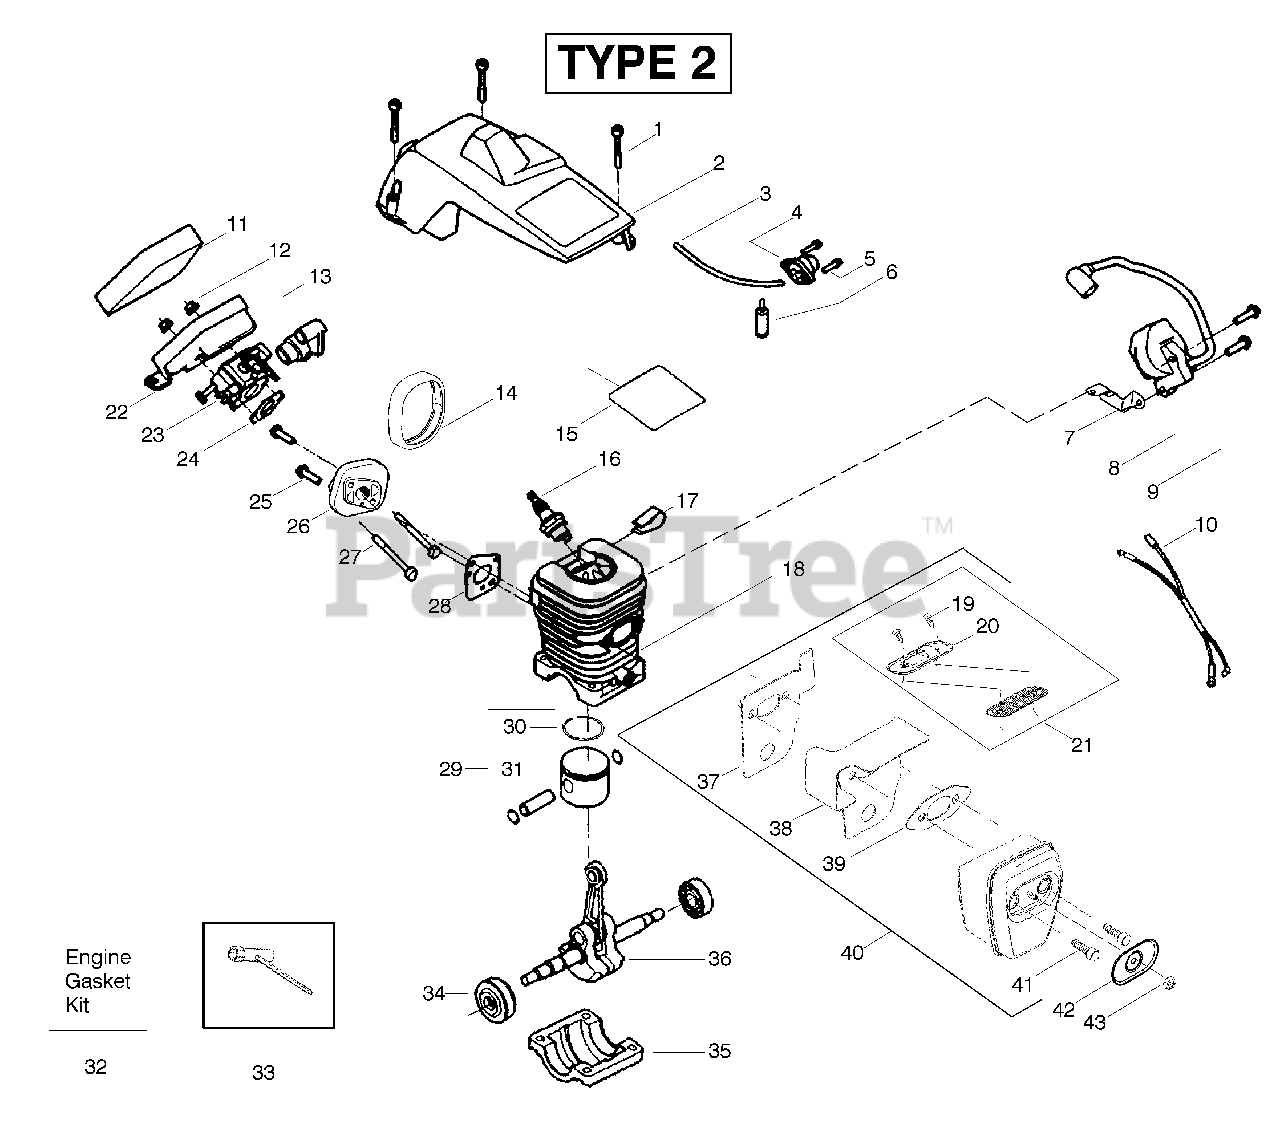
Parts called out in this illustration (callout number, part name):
2	Assy-Cylinder Shield
3	Kit-Fuel Line
4	Assy- Air Purge
6	Assy-Fuel Pick-up
7	Strap-Ground
8	Ignition Module
10	Assy-Wire Harness
11	Foam- Air Filter
13	Grommet-Carb Adjust
14	Seal-Carb Adapter
15	Reflector-Heat
16	Spark Plug
17	Clip-High Tension Lead
18	Cylinder
19	Screw-Outlet cover
20	Cover - Outlet
21	Kit-Spark Arrestor
22	Air Filter Housing
23	Kit-Carburetor (Walbro-WT-89)
24	Gasket-Carb.
26	Carb. Adapter
28	Gasket- Adaptor
29	Kit-Piston
30	Ring-Piston
31	Retainer-Piston Pin
32	Kit-Engine Gasket
33	Bar Wrench
34	Assy-Seal & Bearing
35	Cap-Crankcase
36	Assy-Crankshaft
37	Backplate
38	Guide-Outlet
39	Gasket-Muffler
40	Assy-Muffler
41	Bolt-Muffler
42	Cover-Bolt
43	Nut-Brass
